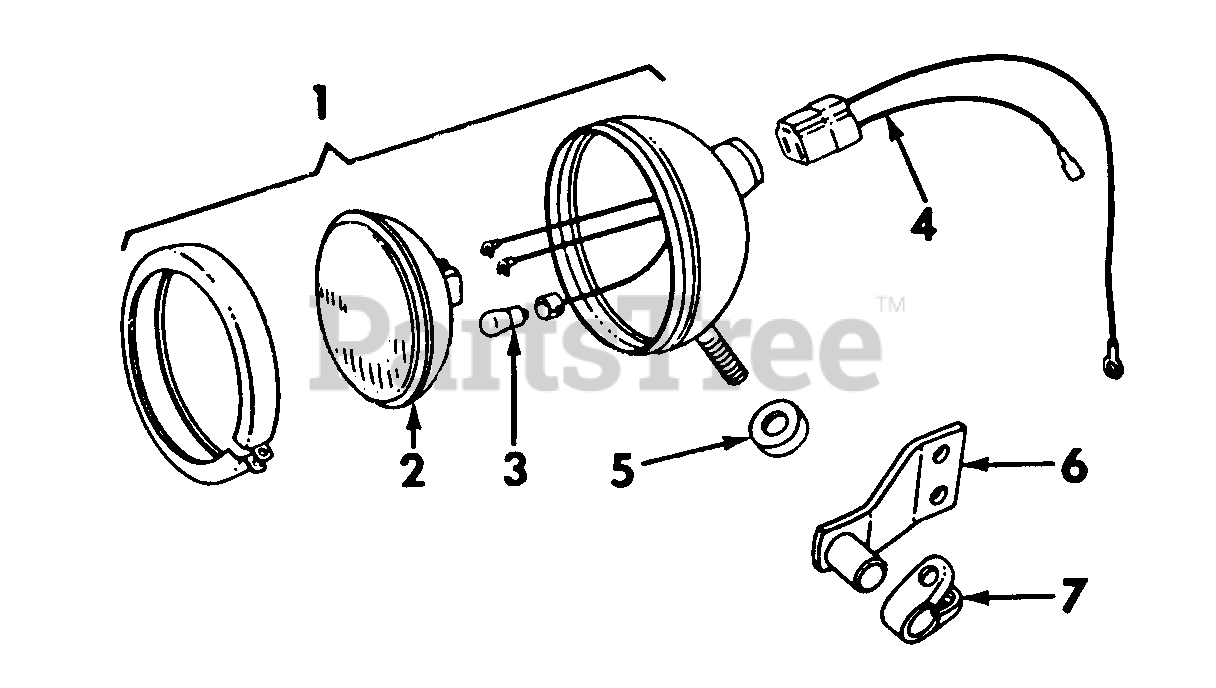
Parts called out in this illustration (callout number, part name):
1	LIGHT ASSY. COMBINATION REAR AND TAIL - 12 VOLT
2	UNIT, SEALED BEAM -12 VOLT
3	LAMP, NO. 1003 -12 VOLT
4	CABLE ASSY COMBINATION REAR LIGHT CONNECTOR
5	SPACER, REAR LIGHT
6	BRACKET ASSY, REAR LIGHT
7	CLAMP REAR LIGHT
